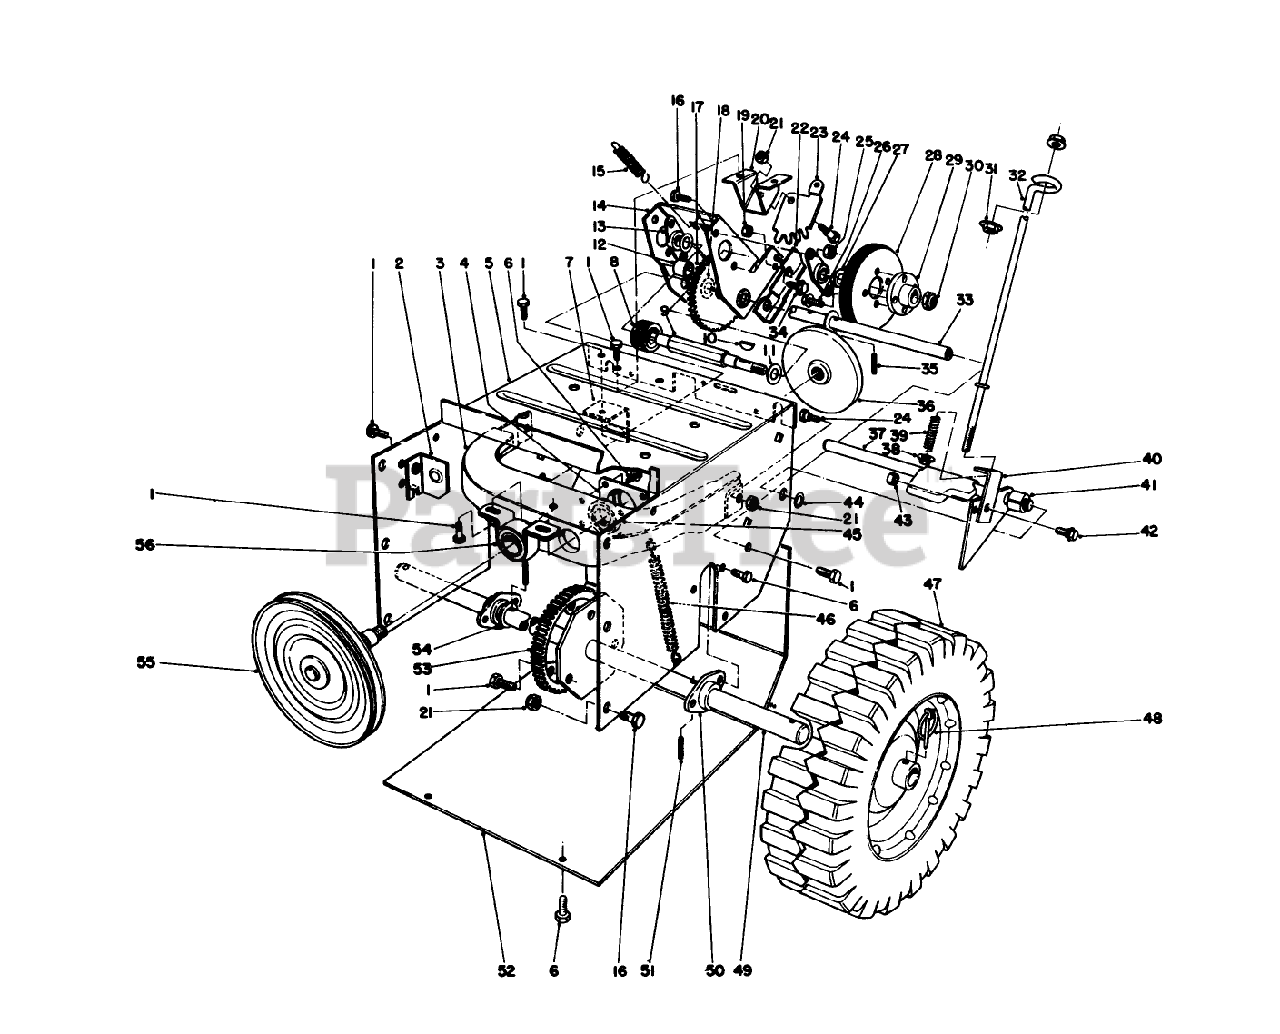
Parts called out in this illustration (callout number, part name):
1	SCREW-THD ROLL, HWH
3	FRICTION PLT FRAME
4	CUP-BEARING
6	Bolt 1/4-20
7	BRACKET-MOUNT, REAR
8	PINION
9	SHAFT-WHEEL, FRICTION
10	KEY-WOODRUFF
11	WASHER-FLAT
12	5/8ID X 1LG BUSHING
13	BEARING-WHEEL, FRICTION
14	BRACKET-SLIDING
15	SPRING-TRACTION
16	SCREW-HH
17	INTERNAL GEAR AND BUSHING ASM
18	WASHER-SPECIAL
19	NUT-LOCK, NI
20	MOUNT-LEVER
21	NUT-LOCK, NI
22	CAM-RECEIVER
23	GEAR-QUADRANT
24	BOLT-SHOULDER
25	NUT-LOCK, CONE
26	SCREW-HWHTF
27	WASHER-THRUST
28	WHEEL-FRICTION
29	HUB-WHEEL, FRICTION
30	NUT-LOCK, NI
31	NUT-HF
32	ROD-TRACTION, LOWER
33	SHAFT-PIVOT
35	PIN-SPRING
36	PLATE-FRICTION
38	NUT-HHF
39	SPRING
40	BRACKET-TRACTION
41	SPACER
42	SCREW
43	NUT-LOCK, NI
44	RING-RETAINING
45	BEARING-BALL
46	SPRING-PLATE, FRICTION
48	PIN-LYNCH
49	AXLE SHAFT WA
50	BEARING-AXLE
51	PIN-SPRING
53	GEAR-AXLE
54	WASHER-THRUST
